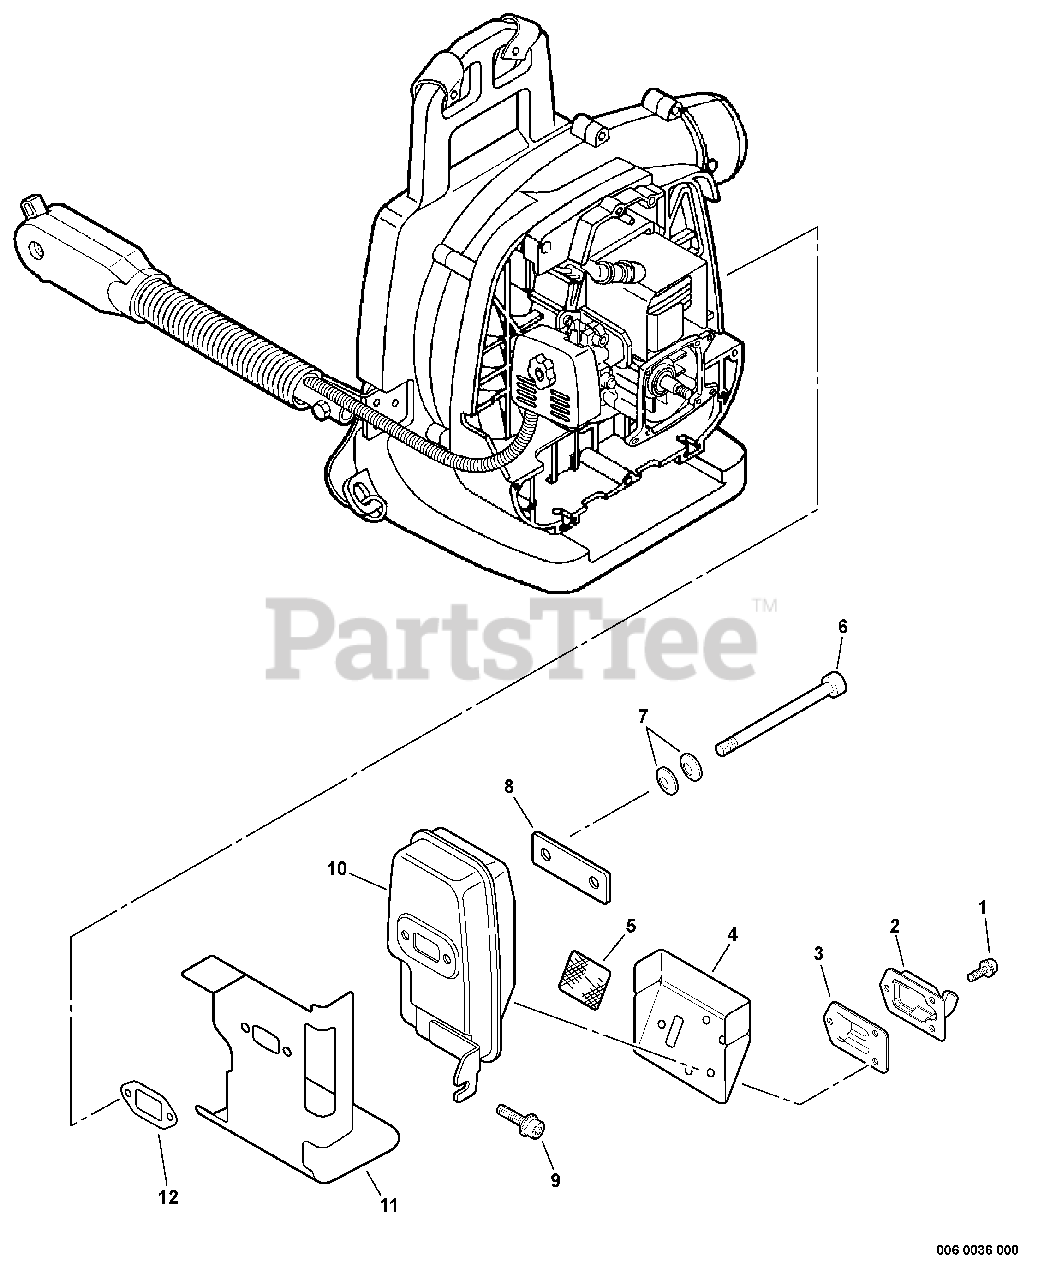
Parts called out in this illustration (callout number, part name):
1	SCREW 4×12
2	GUIDE, EXHAUST
3	GUIDE, EXHAUST
4	GASKET, EXHAUST
5	SCREEN, SPARK ARRESTER
6	BOLT M5×65
7	CONICAL WASHER
8	PLATE, EYE
9	BOLT 5×16
10	MUFFLER
11	HEAT SHIELD, EXHAUST
12	GASKET, EXHAUST
